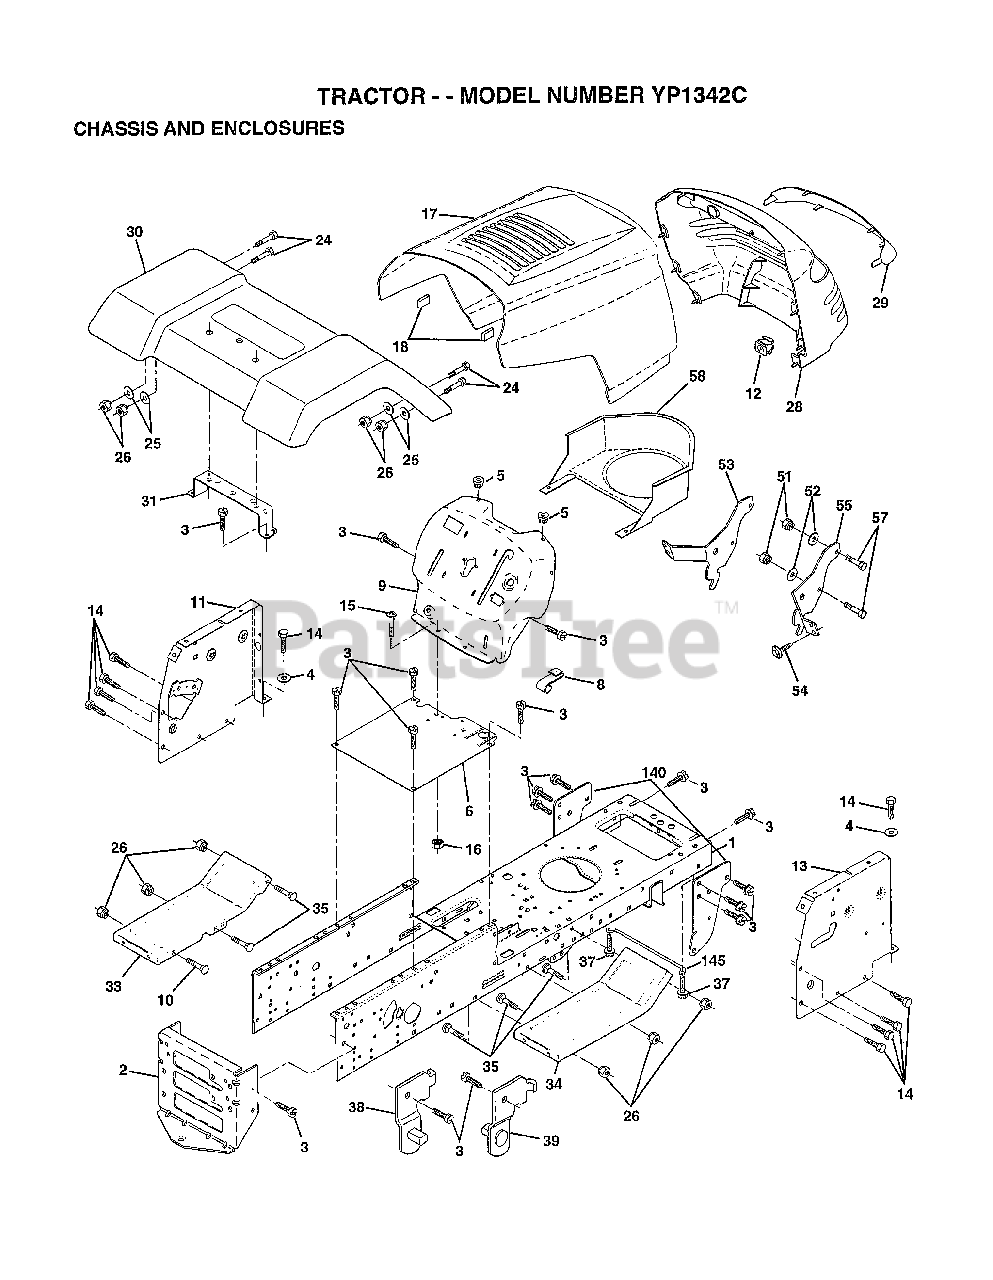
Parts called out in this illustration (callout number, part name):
3	SCREW
4	WASHER
5	BUMPER-HOOD/DASH
6	SADDLE
8	CLIP.RETAINER
9	DASH.SILKSCREEN
11	"PANEL-DASH,LH"
12	CLIP.TINNERMAN
13	"PANEL-DASH,RH"
14	SCREW LT
15	SCREW
17	"HOOD W/TRIM,MS428"
24	BOLT
25	WASHER
26	NUT
28	GRILL PRIVATE LABLE BLK
29	LENS.EURO.W/DECAL
30	FENDER ASM
31	BRKT FENDER
33	FOOTREST PNT LH
34	FOOTREST.RH.LT/GT
35	BOLT
38	BRACKET ASM LH
39	BRACKET ASM RH
51	NUT
52	WASHER
53	BRACKET.GRILLE.LH
54	SCREW.HEX.WS.HD
55	BRACKET.GRILLE.RH
58	AIR DUCT
140	BRKT SUSPENSION
145	"ROD POVOT,CHASSIS"
